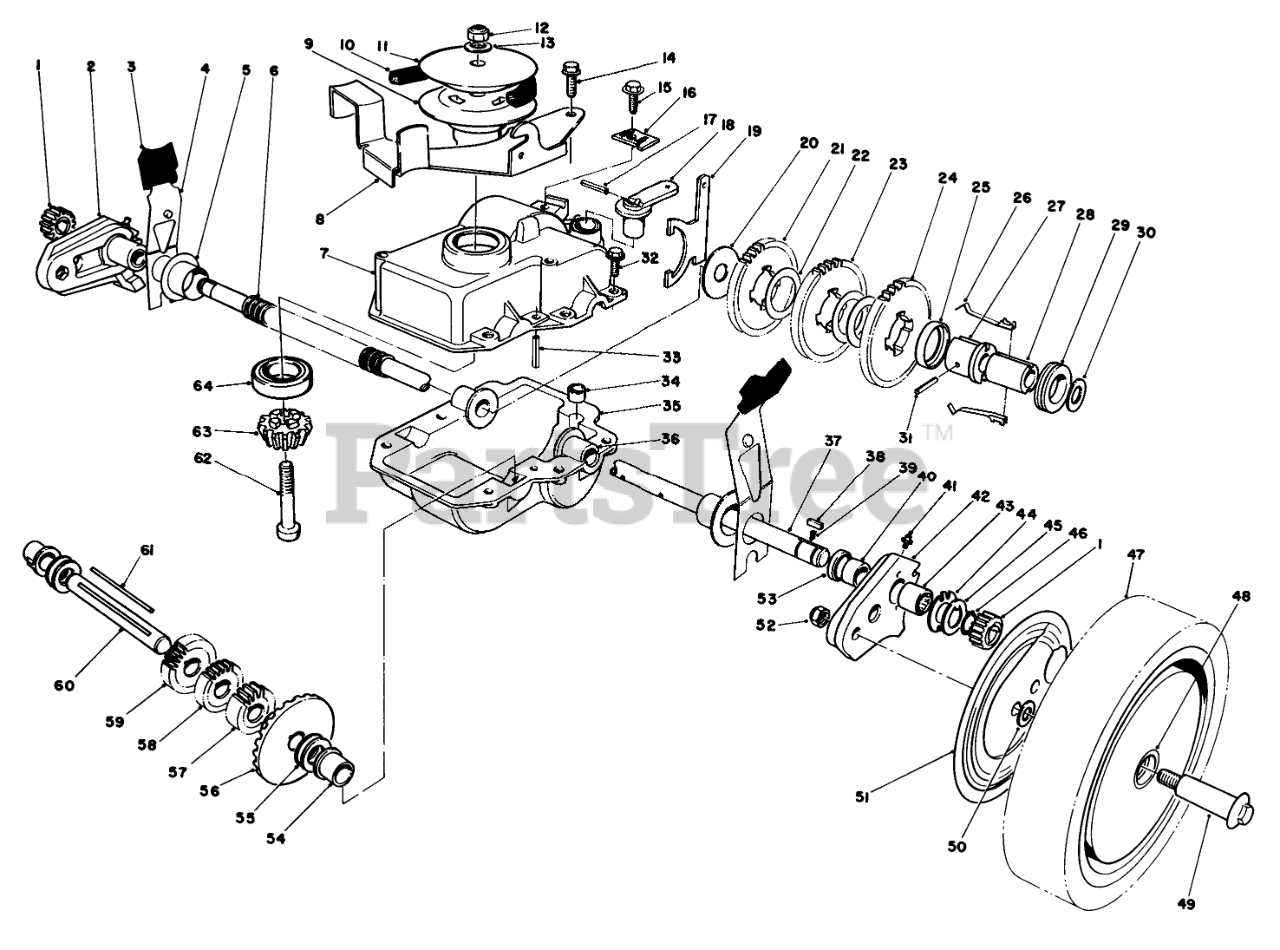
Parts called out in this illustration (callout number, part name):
1	GEAR-PINION
2	Pivot Arm Assembly-RH. (Incl. Ref. #40, 41, 43 & 53)
3	KNOB-ARM
4	SPRING ARM ASM SP
5	CAP-END
6	CONDUIT-CONVOLUTED, SPLIT
7	Case-Upper
8	BELT GUIDE BRKTB
9	PULLEY-LOWER HALF
10	V-BELT
11	PULLEY-UPPER HALF
12	NUT-LOCK, NI
13	WASHER-FLAT
14	SCREW
15	SCREW-HWHTF
16	Cable Clamp
17	PIN-COIL
18	LEVER-SHIFT
19	Shift Yoke
20	WASHER
21	GEAR-38T
22	WASHER
23	GEAR-42T
25	RETAINER-KEY
26	KEY-SHIFT
27	SLEEVE-GEAR
28	SLEEVE
29	COLLAR-SHIFT
30	WASHER-PLAIN
31	PIN-SPRING
32	SCREW-HWHTF
33	ROLL PIN 3/16 X 1 IN
34	BUSHING-YOKE
35	LOWER GEAR CASE CAST
36	Bushing-Output Shaft
37	Output Shaft
38	KEY RECTANGULAR
39	SPRING-COMPRESSION
40	BUSHING
41	FITTING-GREASE
42	Pivot Arm Assembly-L.H. (Incl. Ref. #40, 41, 43 & 53)
43	BEARING-ROLLER
44	INNER THRUST WASHER
45	WASHER-THRUST, OUTER
46	RING-RETAINING
47	Wheel, Tire & Gear Assembly (Incl. Ref. #48)
48	BUSHING
49	WHEEL BOLT
50	WASHER
51	WHEEL COVER
52	NUT-LOCK
53	SEAL-OIL
54	BUSHING
55	WASHER-THRUST
56	BEVEL GEAR
57	GEAR-12T
58	GEAR-14T
59	GEAR-18T
60	INTERMEDIATE SHAFT
62	Screw-Socket Hd
63	BEVEL PINION
64	BEARING-BALL
